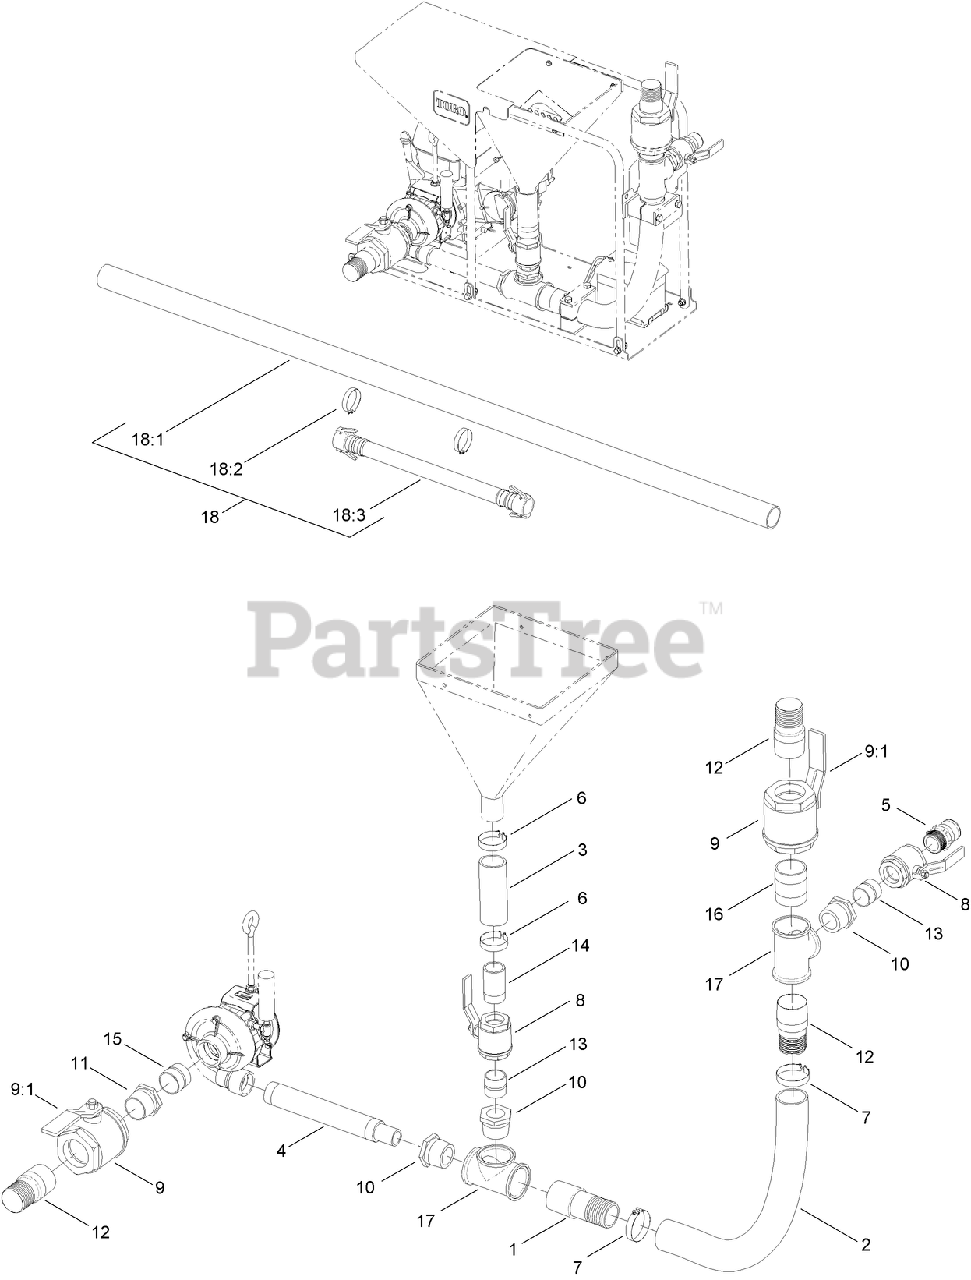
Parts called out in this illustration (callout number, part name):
1	VENTURI
2	HOSE-SUCTION, WATER
3	HOSE-SUCTION, WATER
4	TUBE-JET
5	ADAPTER-MALE
6	CLAMP, T-BOLT
7	CLAMP-T BOLT
8	VALVE-BALL (2.0)
9	VALVE-BALL (3.0)
9:1	HANDLE-BALL, 3.0 VALVE
10	BUSHING-PIPE
11	BUSHING-PIPE
12	NIPPLE-COMBINATION
13	NIPPLE-PIPE
14	NIPPLE-PIPE
15	NIPPLE-PIPE
16	NIPPLE-PIPE
17	TEE-PIPE
18	SHIP KIT HOSE ASM
18:1	HOSE-SUCTION, WATER
18:2	CLAMP-T BOLT
18:3	DISCHARGE HOSE ASM
